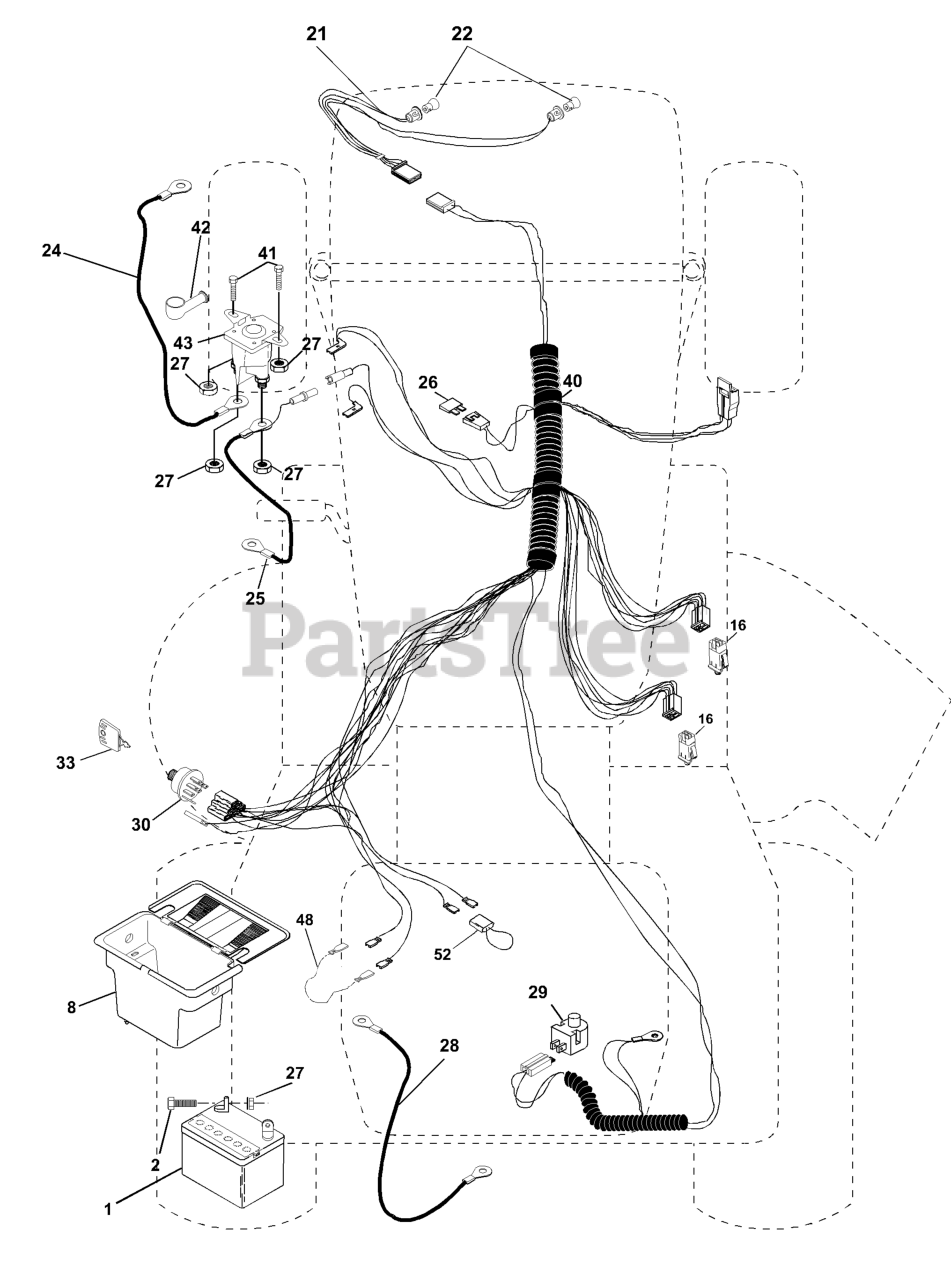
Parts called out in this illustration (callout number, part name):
1	BATTERY 12 VOLT 25 AMP
2	BOLT.HEX.1/4.X.3/4.DICHROMATE
8	CASE BATTERY MECH HINGE
16	SWITCH INTERLOCK
24	BATTERY CABLE GT
25	CABLE BATTERY
26	FUSE 20AMP
27	NUT
28	CABLE T
29	RP.SWITCH.PLUNGER.NC.GRAY
30	IGNITION SWITCH
33	KEY MLD GEN DELTA
40	HARNESS, IGN. LTH120
41	BOLT
42	TERMINAL COVER
43	REPL BY 532 1461-54
48	ADAPTER.AMMETER
52	WIRE PROTECTION LOOP
